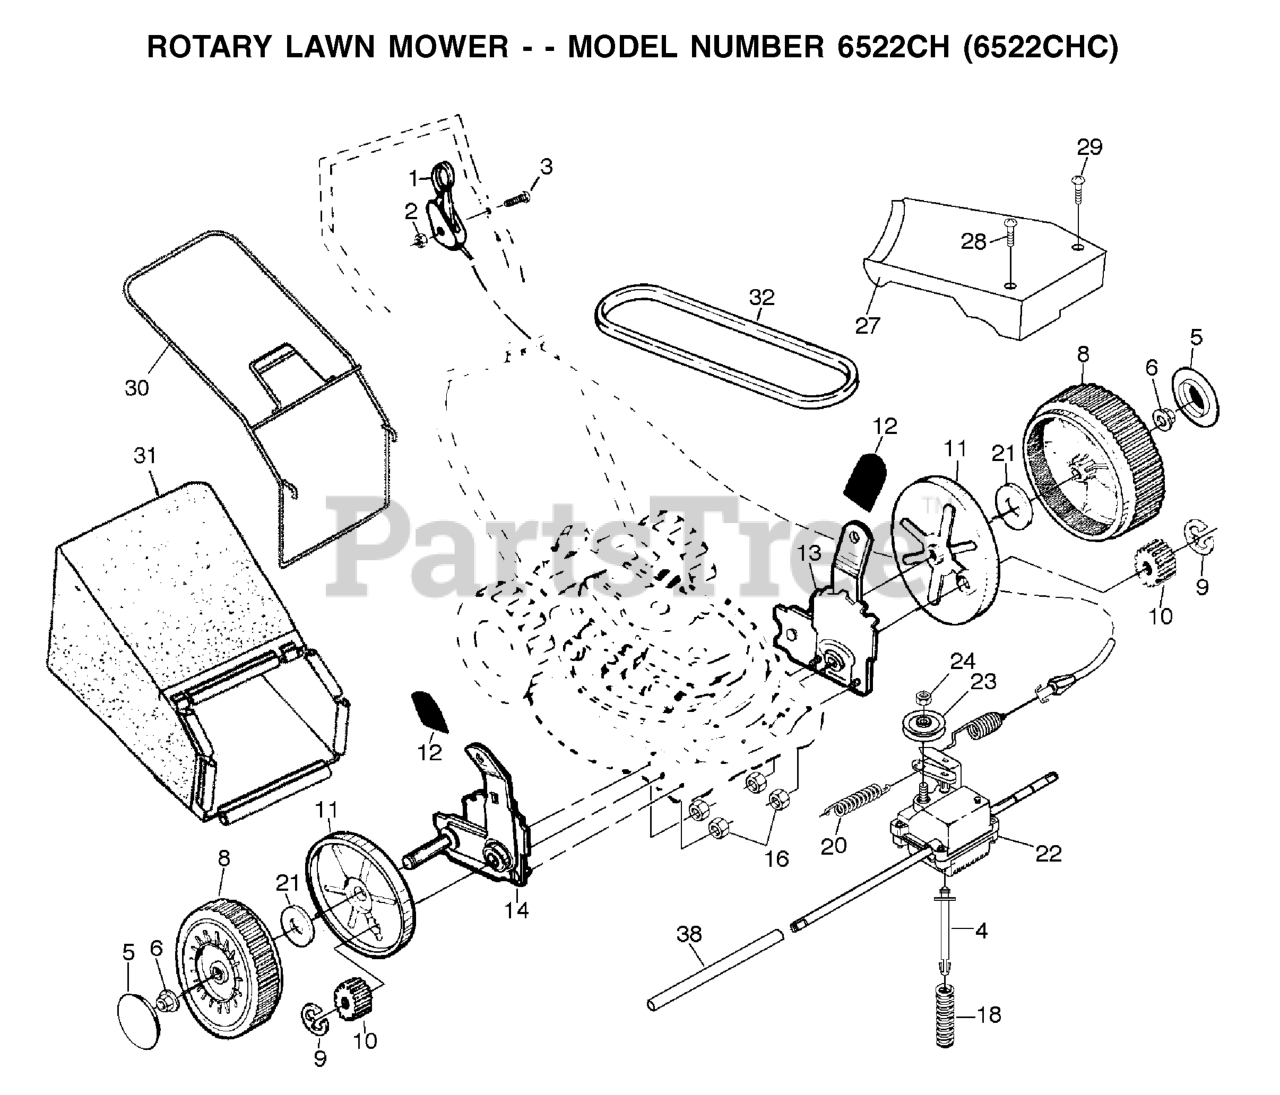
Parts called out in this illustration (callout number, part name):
1	DRIVE CONTROL
2	LOCK NUT
3	SCREW.PAN.HEAD
4	SPRING RETAINER
5	CAP.HUB.BLACK.WALK
6	NUT
8	WHEEL
9	E-RING 7/16 RE
10	PINION GEAR
11	DUST COVER, WHEEL
13	WHEEL ADJ ASM (L)
14	KIT.ADJUSTER.ASM.(151514).RT
16	NUT
18	SPRING.EXTENSION
21	WASHER FLUT
22	GEAR CASE ASMBLY
23	PULLEY
24	FLANGED LOCKNUT 3/8-16 ZINC
27	DRIVE COVER-GRAY
29	SCREW.SLOT.TORX.
30	CATCHER FRAME
32	BELT THERM .32
38	DRV SHAFT TUBE PM
